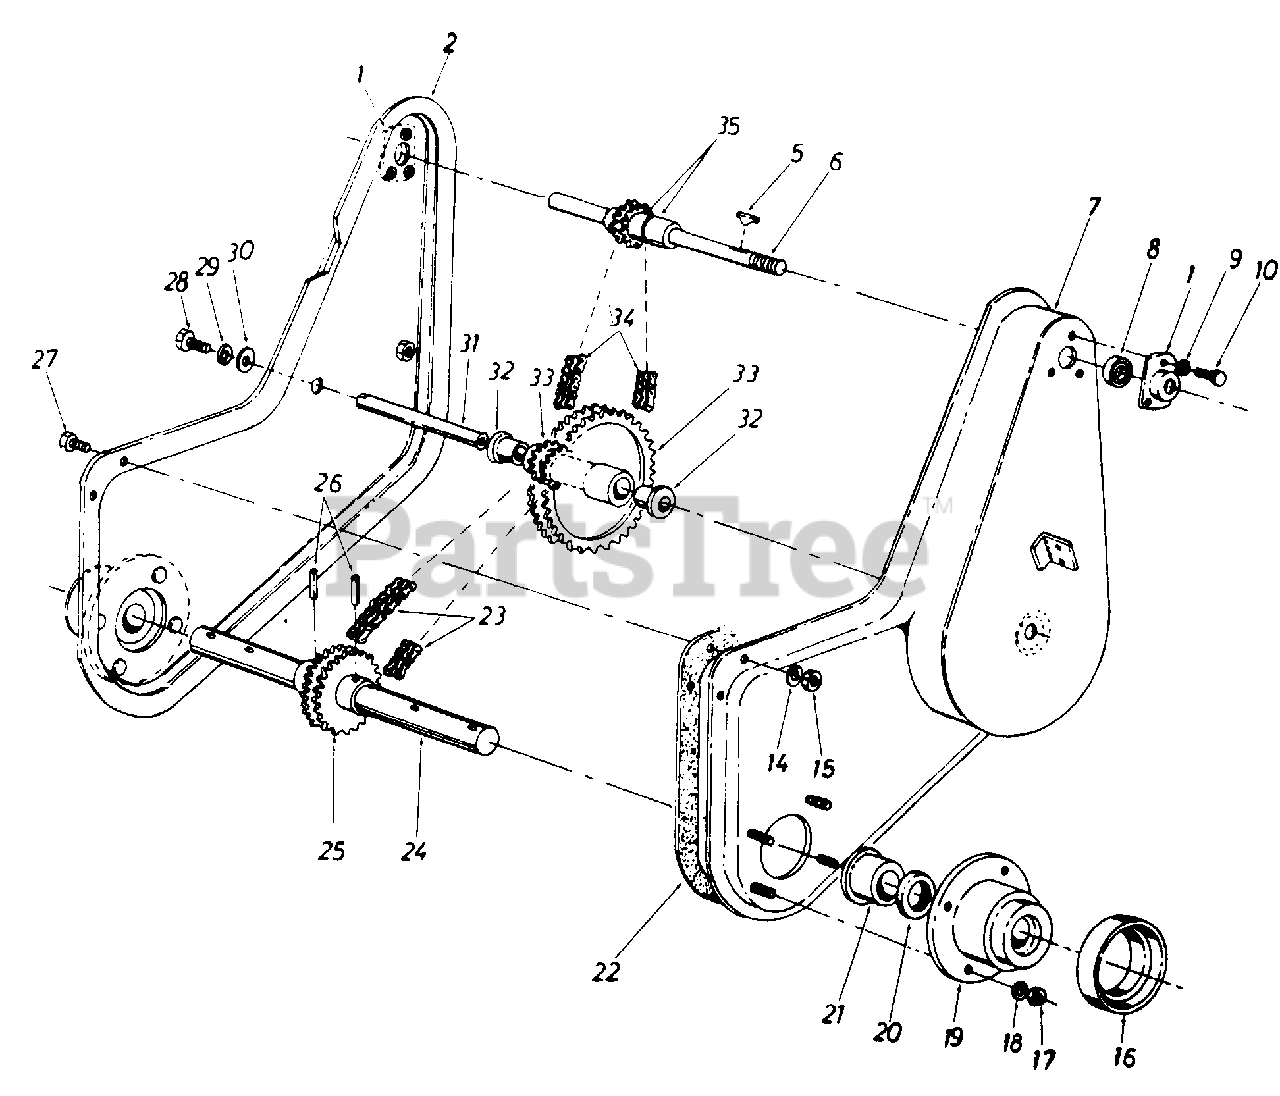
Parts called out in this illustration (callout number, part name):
1	Bearing Housing 1.875" Dia.
6	Input Shaft Assembly
9	L-Wash. 1/4" I.D.
10	Hex Bolt 1/4-20 x .62" Lg.
14	L-Wash. 1/4" I.D.
15	Hex Cent. L-Nut 1/4-20 Thd.
16	Dust Cap Cover
17	Hex Cent. L-Nut 5/16-18 Thd.
18	L-Wash. 5/16" I.D.
19	Cast Bearing Housing
20	Oil Seal
21	Flange Bearing 1.25" I.D. x 1.75" O.D.
22	Gasket
23	Roller Chain #40-2 x 34.0 Lg.
24	Tine Shaft
25	Double Sprocket T242 Teeth 1/2" Pitch
26	Spiral Pin 3/8" Dia. x 2.00 Lg.
27	Hex Bolt 1/2-20 x .62" Lg.
28	Hex Bolt 5/16-18 x .75n Lg.
29	L-Wash. 5/16" I.D.
30	Fl-Wash. 5/16" I.D.
31	Sprocket Shaft
32	Flange Bearing .62" I.D. x .75" O.D.
33	Double Sprocket Assembly
34	Roller Chain #35-2 x 36.75" Lg.
35	Spacer 5/8" I.D. x 7/8" O.D.
